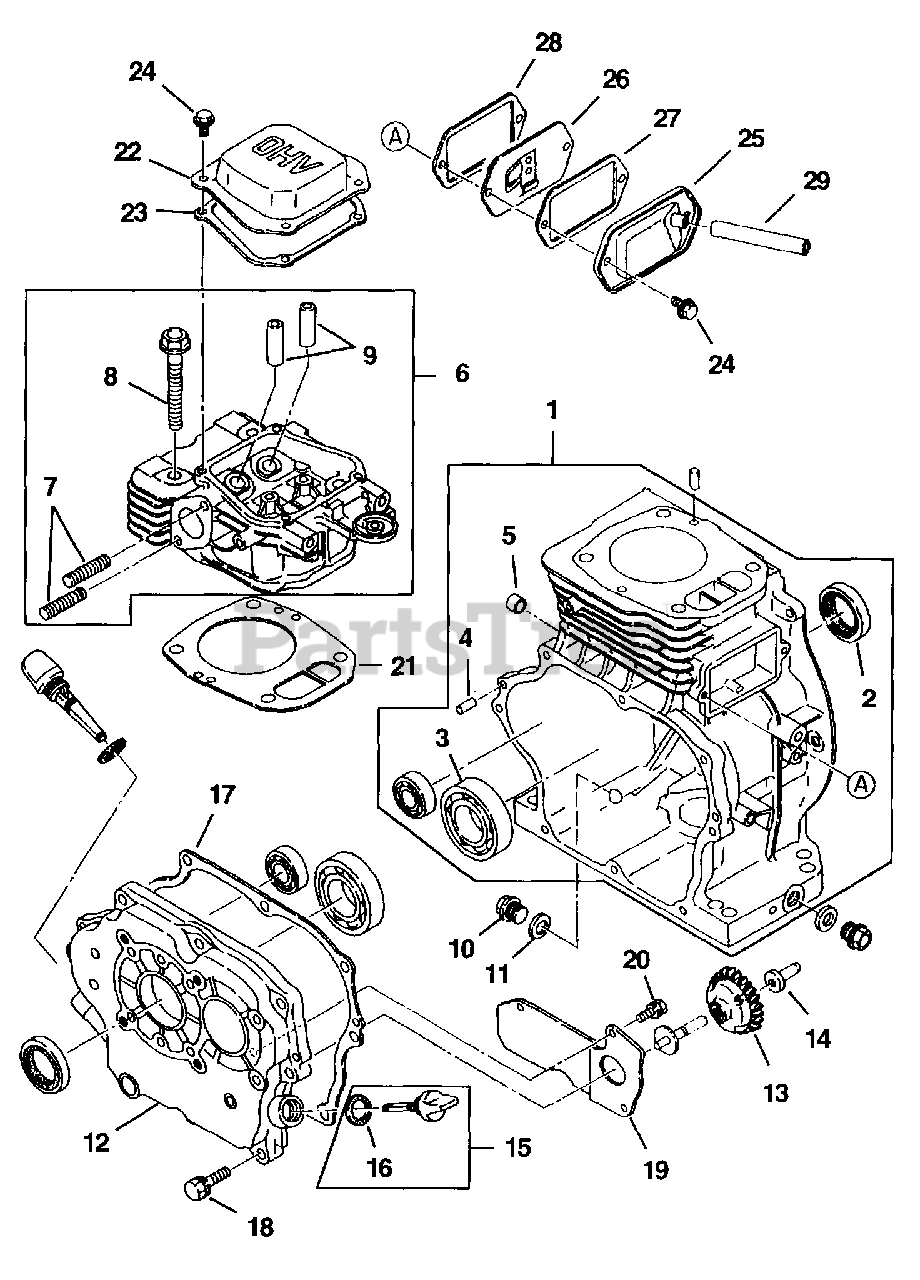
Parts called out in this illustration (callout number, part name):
1	Crankcase-LRX4500
2	Oil seal
3	Ball bearing
4	Dowel pin
6	Cylinder head
8	Flange bolt M10 x 75
9	Valve guide
12	Main bearing cover
13	Governor gear cp
14	Governor sleeve
15	Oil gauge & gasket set
17	Bearing cover gasket
18	Bolt & washer M8 x 30
19	Oil shelter
20	Screw & washer
21	Head gasket
22	Rocker cover
23	Rocker cover gasket
24	Flange bolt M6 x 12
25	Breather cover
26	Breather plate
27	Breather cover gasket
28	Breather plate gasket
29	Rubber pipe
